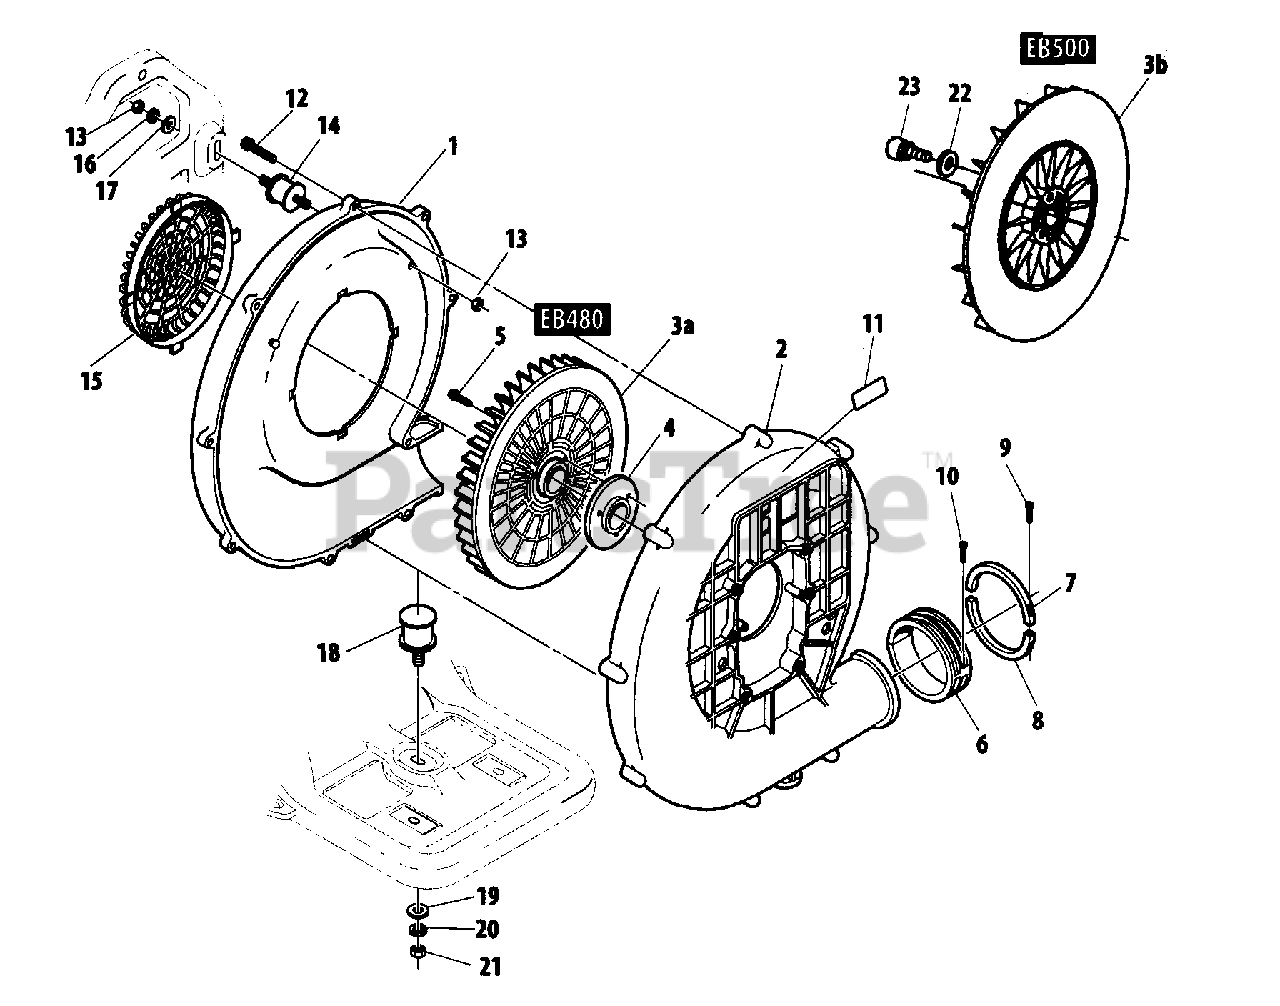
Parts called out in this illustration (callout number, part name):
1	COVER, FAN - INNER
2	COVER, FAN - OUTER
3A	IMPELLER
3B	IMPELLER
5	SCREW - 6X40
6	SLEEVE
7	RING A
8	RING - B
9	SCREW
10	SCREW -- TAPPING
12	SCREW - 5 -- TAPPING
14	CUSHION
15	COVER, INTAKE
16	LOCKWASHER - 5
17	WASHER
18	CUSHION
20	LOCKWASHER - 6
21	NUT - 6
22	WASHER - 6
23	SCREW - 6X25
